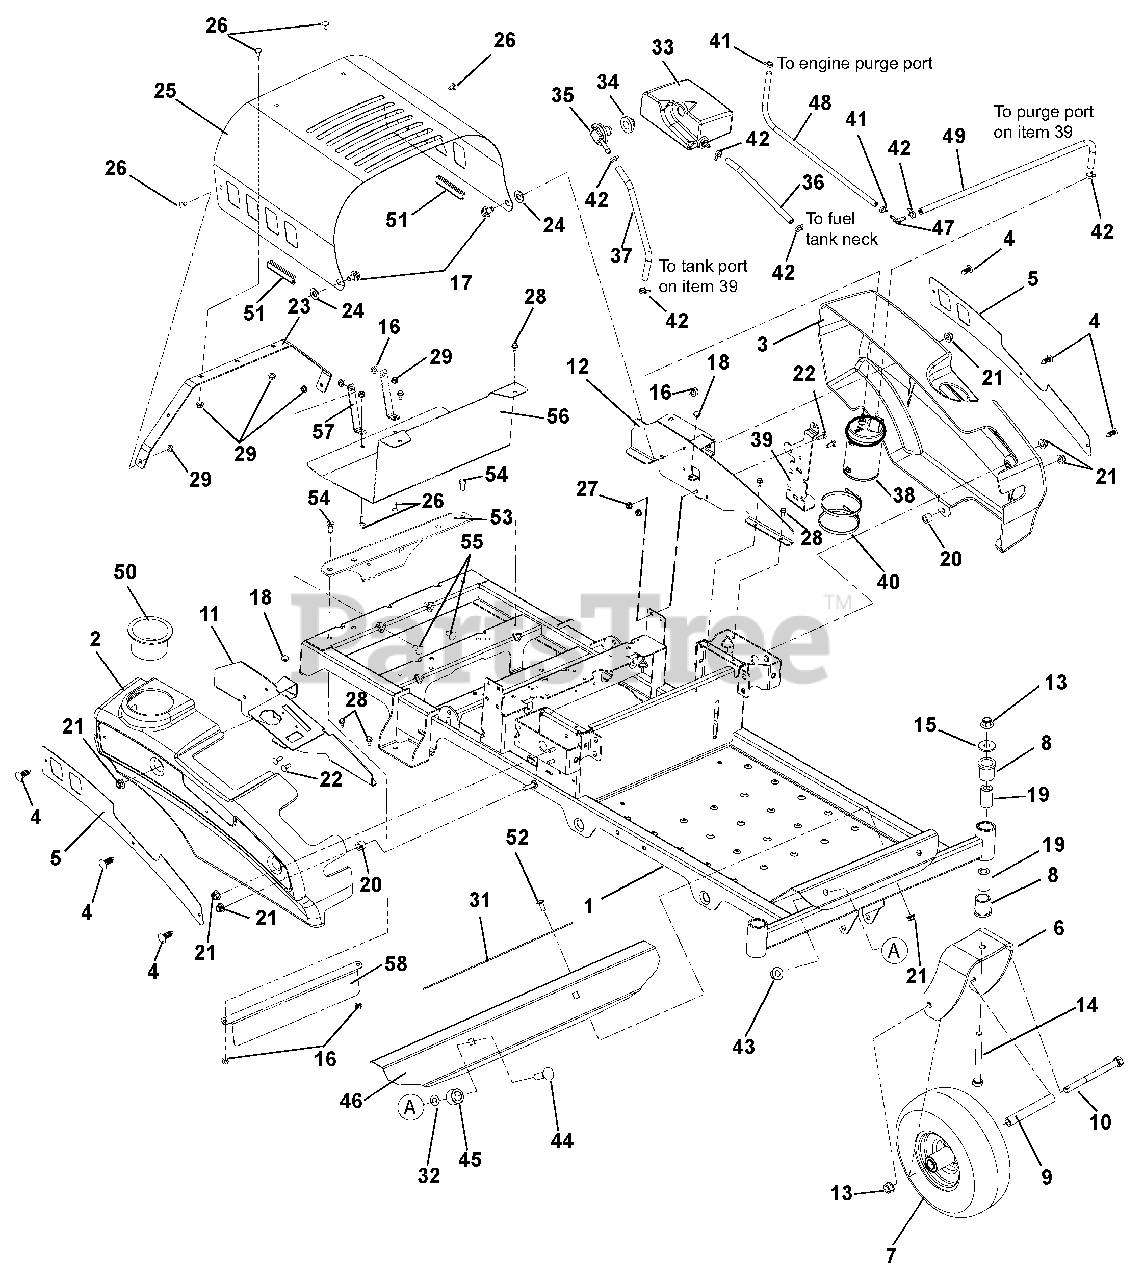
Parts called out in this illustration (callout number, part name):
1	KIT, ZOOM/ZT FRAME W/ DECALS
2	FENDER, RH
3	FENDER, LH
4	RIVET, .25 NYLON PANEL
5	PLATE, FENDER
6	WMT, CASTER FORK
7	TIRE/WHEEL ASSY, 11X4-5
8	BSHG-FLG 1.00X1.25X1.50X1.50
9	SPACER, ROLLED WHEEL
10	@BLT-HEX .50-13X6.50 GR5 YWZC
11	WLDMT, RH FENDER MOUNT
12	WLDMT, LH FENDER MOUNT
13	@NUT-LK-TOP-FLG .50-13 YWZC
14	@BLT-HEX .50-13X5.00 GR5 YWZC
15	WSHR-FL-STL.511X1.441X.125 YWZ
16	@NUT-LK-TOP-FLG .38-16 YWZC
17	BOLT-SHLDR .375-16X.150
18	BUMPER GROMMET
19	SPACER, CASTER .50X1.00X1.84
20	BSHG-SLV .391X.688X.52 PM
21	@NUT-LK-NYL-FLG .31-18 YWZC
22	@BLT-RDHDSQNK .25-20X.75 G5YZ
23	BRACE, HOOD
24	WSHR-FL-NYL .518X1.000X.080
25	HOOD, ZOOM
26	@BLT-RDHDSQNK .25-20X.50 G5YZ
27	@NUT-LK-NYL-FLG .25-20 YWZC
28	SCR-TAP .25-20X.50 HWH TR YWZ
29	@NUT-LK-TOP-FLG .25-20 YWZC
31	GRIP, ADHESIVE (1" X 16" BLK)
32	NUT-PUSH, .50
33	EXPANSION TANK SUB ASSY
34	GROMMET, REMOTE VENT NITRILE
35	VALVE, COMBINATION
36	HOSE, .25 LOW-PERM BULK GAS
37	HOSE, .25 LOW-PERM BULK GAS
38	CARBON CANISTER, 300CC
39	BRKT-MOUNT, CANISTER BBZ
40	P-PLASTIC TIE STRAP LARGE
41	CLAMP-HOSE, SPRING .188
42	CLAMP, FUEL LINE
43	@NUT-LK-NYL-FLG .50-13 YWZC
44	@BLT-RDHDSQNK .50-13X1.75 G5YZ
45	TUBE, UPPER CONTROL PIVOT
46	FOOTREST
47	FITTING-3/16X1/4 90DEGREE VAC
48	HOSE, .188 LOW-PERM BULK GAS
49	HOSE, .25 LOW-PERM BULK GAS
50	CUPHOLDER, SNAP-IN 3.75OD
51	EDGING, CLUTCH PADDLE - 2.00"
52	@BLT-RDHDSQNK .31-18X.75 G5YZ
53	PLATE, BBZ HITCH KIT PLATE
54	@BLT-HEX .38-16X1.00 GR5 YWZC
55	@BLT-RDHDSQNK .38-16X1.00 G5YZ
56	GUARD, HEAT SHIELD (ZOOM/ZT)
57	STRAP, HEAT SHIELD (ZOOM/ZT)
58	GUARD, HOT SURFACE (ZOOM/ZT)
